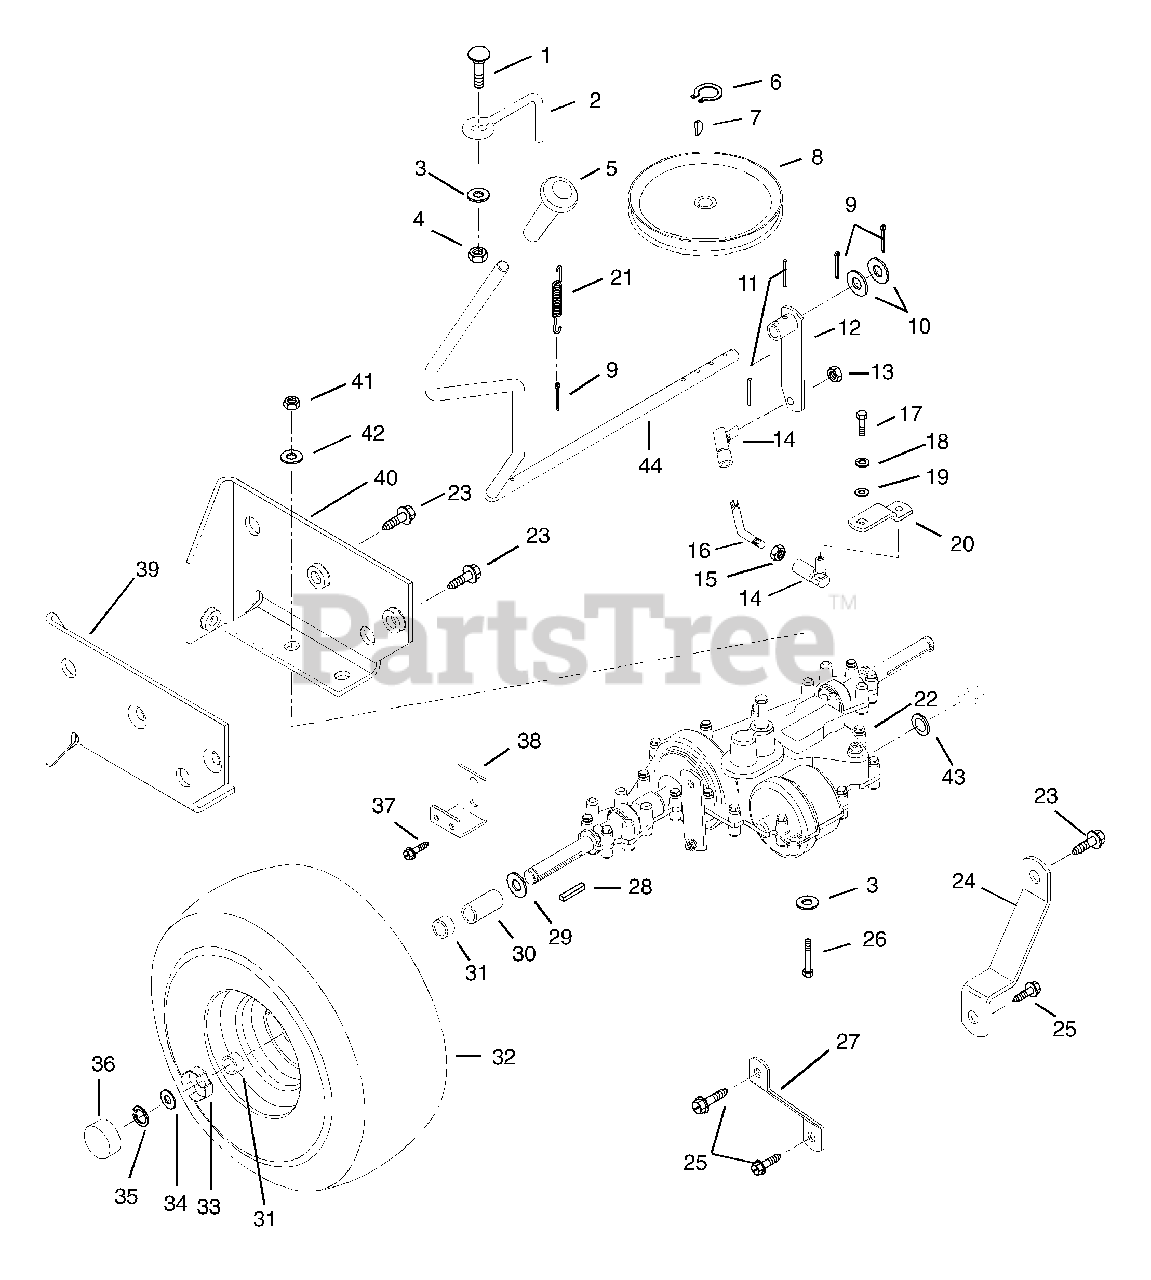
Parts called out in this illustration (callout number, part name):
1	BLT-RDHDSQSHK.31-18X.75 GR2 YW
2	FINGER - BELT
3	@WSHR-FL-STL.344X.688X.065YWZC
4	@NUT-LK-CTR .31-18 YWZC
6	RG-RTNG-EXT .625X.035
7	KEY-WDRF .188X.75X.313 SAE 9
8	PLY-TRANS 7.00X.626
9	@PIN-CTR .12X1.00 EXTPRSQCT YZ
10	WSHR-FL-STL .52X.827X.062 YWZC
11	PIN-GRV .188X1.25 TP A
12	ARM & HUB
13	NUT-CTRLK .31-24 YWZC
14	BALL JOINT- SNAP IN
15	NUT-JAM .31-24 YWZC
16	LINK - SHIFT
17	BLT-HEX .25-28X.75 GR5 YWZC
18	WSHR-LK .250X.077 HVY YWZC
19	WSHR-FL-STL .328X1.0X.094 YWZC
20	ARM - SHIFT 6 SPD
21	SG-TENS .063X.44X1.56
22	TRANSAXLE - GEAR 6 SPEED MST
23	@SCR-TAP .38-16X.75 HWH TR YWZ
24	STRAP - TORQUE,LH 6 SPD
25	@SCR-TAP .31-18X.75 HWH TR YWZ
26	@BLT-HEX .31-18X2.50 GR5 YWZC
27	TORQUE STRAP
28	KEY-SQ .188X2.0X.188 SAE 8630
29	WSHR-FL-STL.755X1.375X.062YWZC
30	BSHG-SLV .750X1.125X1.062
31	SPACER .760X1.000X.575
32	T/WHL ASSY 20X8.00-8
33	SPINDLE CUP
34	WSHR-FL-STL.755X1.375X.062YWZC
35	RG-RTNG-EXT .750X.050
36	HUB CAP
37	SCR-TAP .312-18X.50 HWH TR BL
38	SHIFT GUIDE BRACKET
39	MOUNT - TRANS. RH
40	MOUNT - TRANS. LH
41	@NUT-LK-CTR .31-18 YWZC
42	WSHR-FL-STL .328X.875X.062YWZC
43	O-RING .500X.629X.070
44	LEVER - SHIFT
